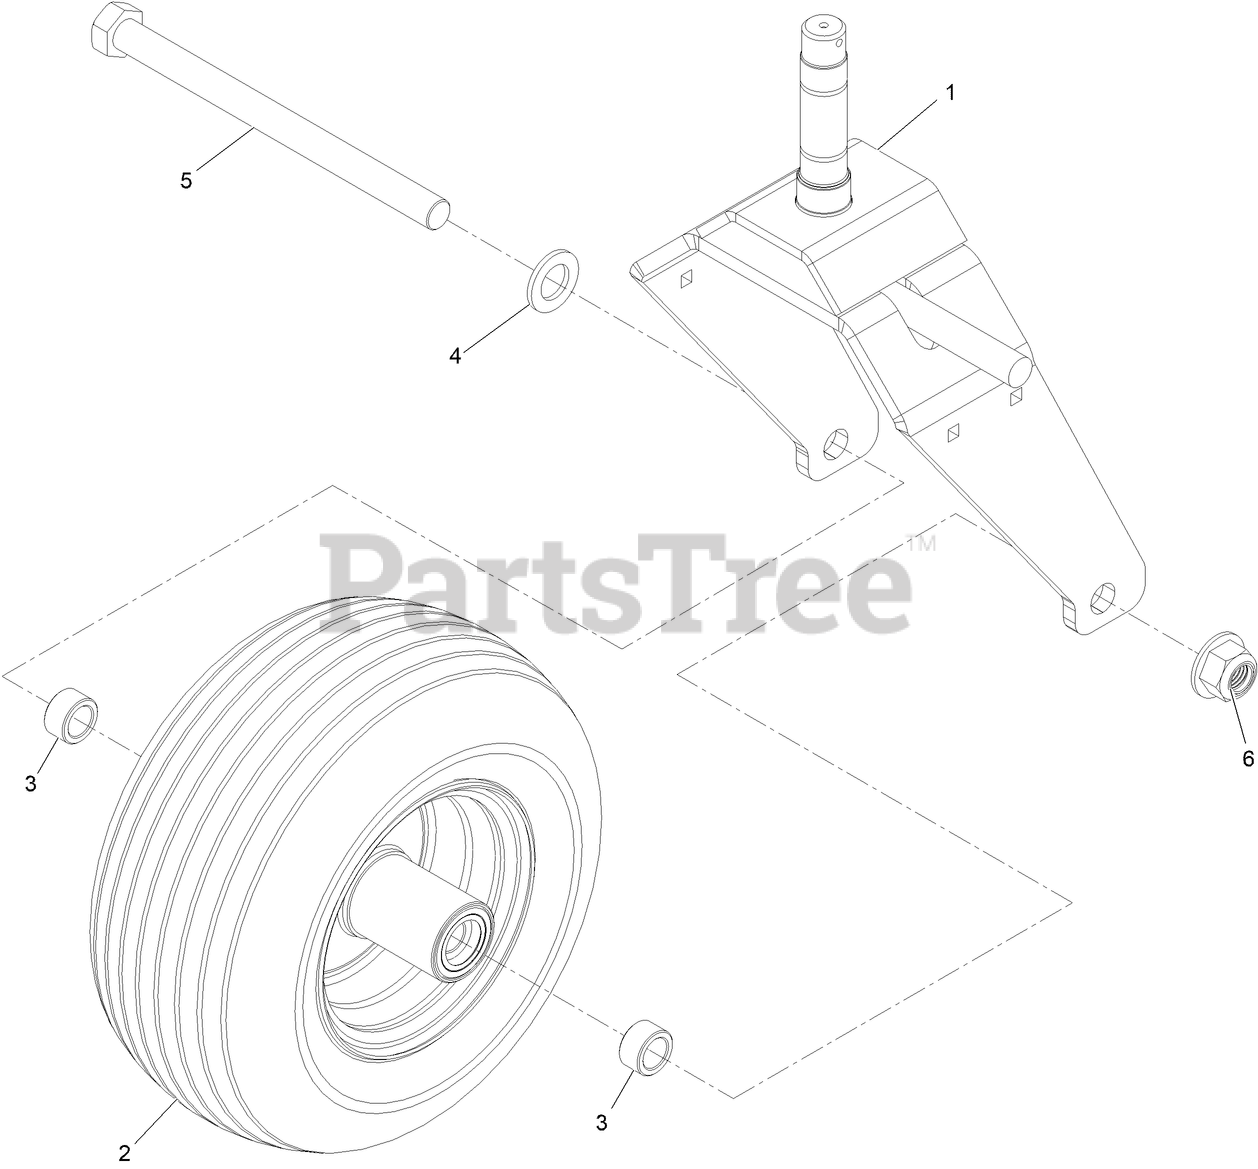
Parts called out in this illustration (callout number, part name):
1	Fork-Caster, RH [red]
2	WHEEL AND TIRE
3	SPACER-AXLE
5	SCREW-HH
